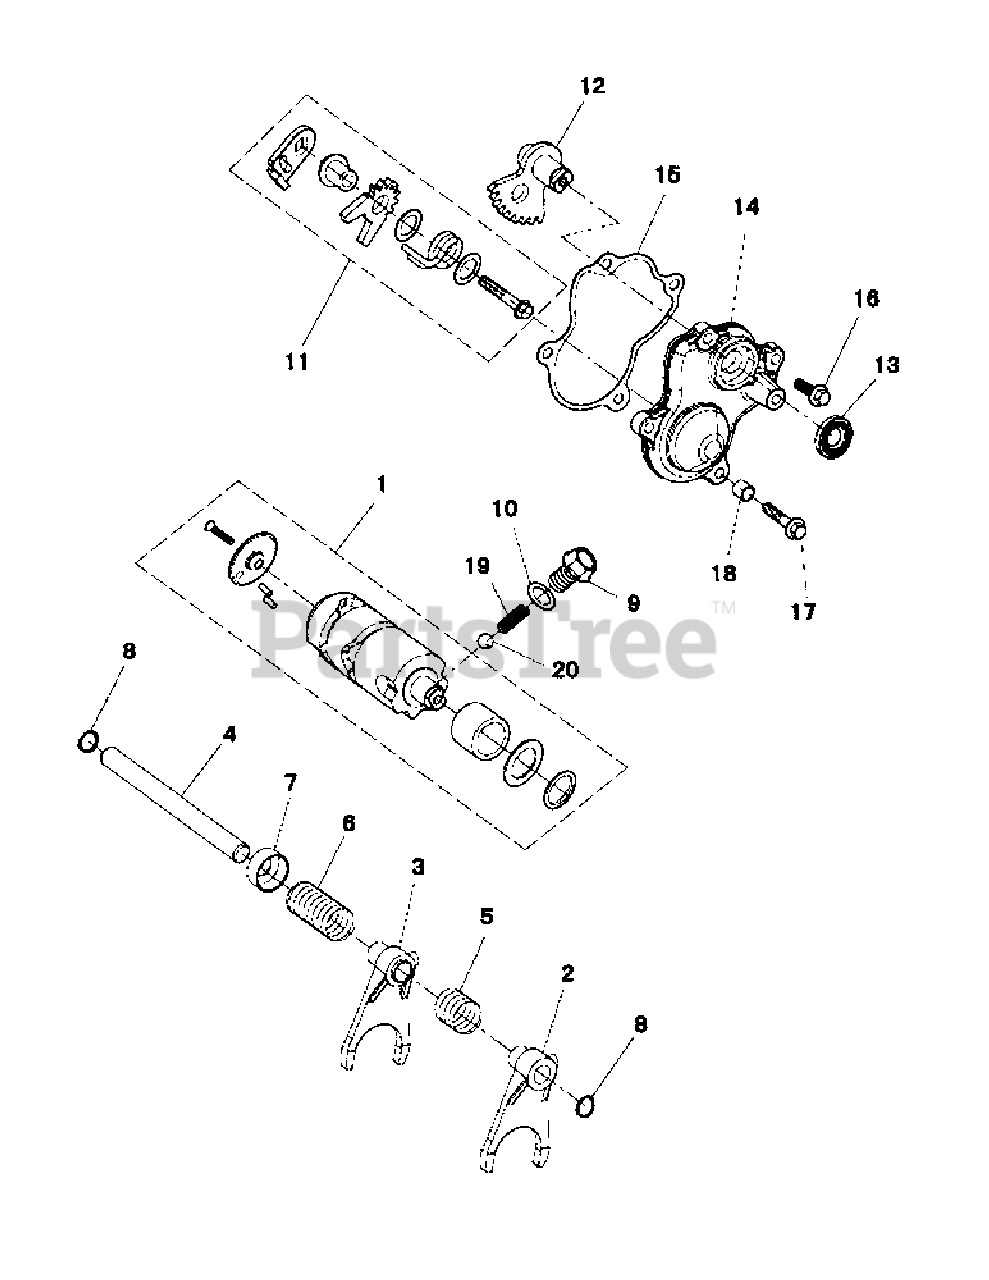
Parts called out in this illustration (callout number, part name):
1	Drum Asm-Shift
3	Fork-H,L Gear
4	Shaft-Gear Shifter
5	Spring-R Gear
6	Spring-H,L Gear
9	Bolt-M14 X 1.5 X 21
11	Shape Drive Gear-Fan
12	Shape Drive Gear-Fan
14	Side Cover-Gear Rocker
15	Washer-Gear Rocker Side Cover
16	Flangebolt M6X20
17	Flangebolt M6X30
19	Spring-24 X 1
20	Steel Ball-Sr9.5
